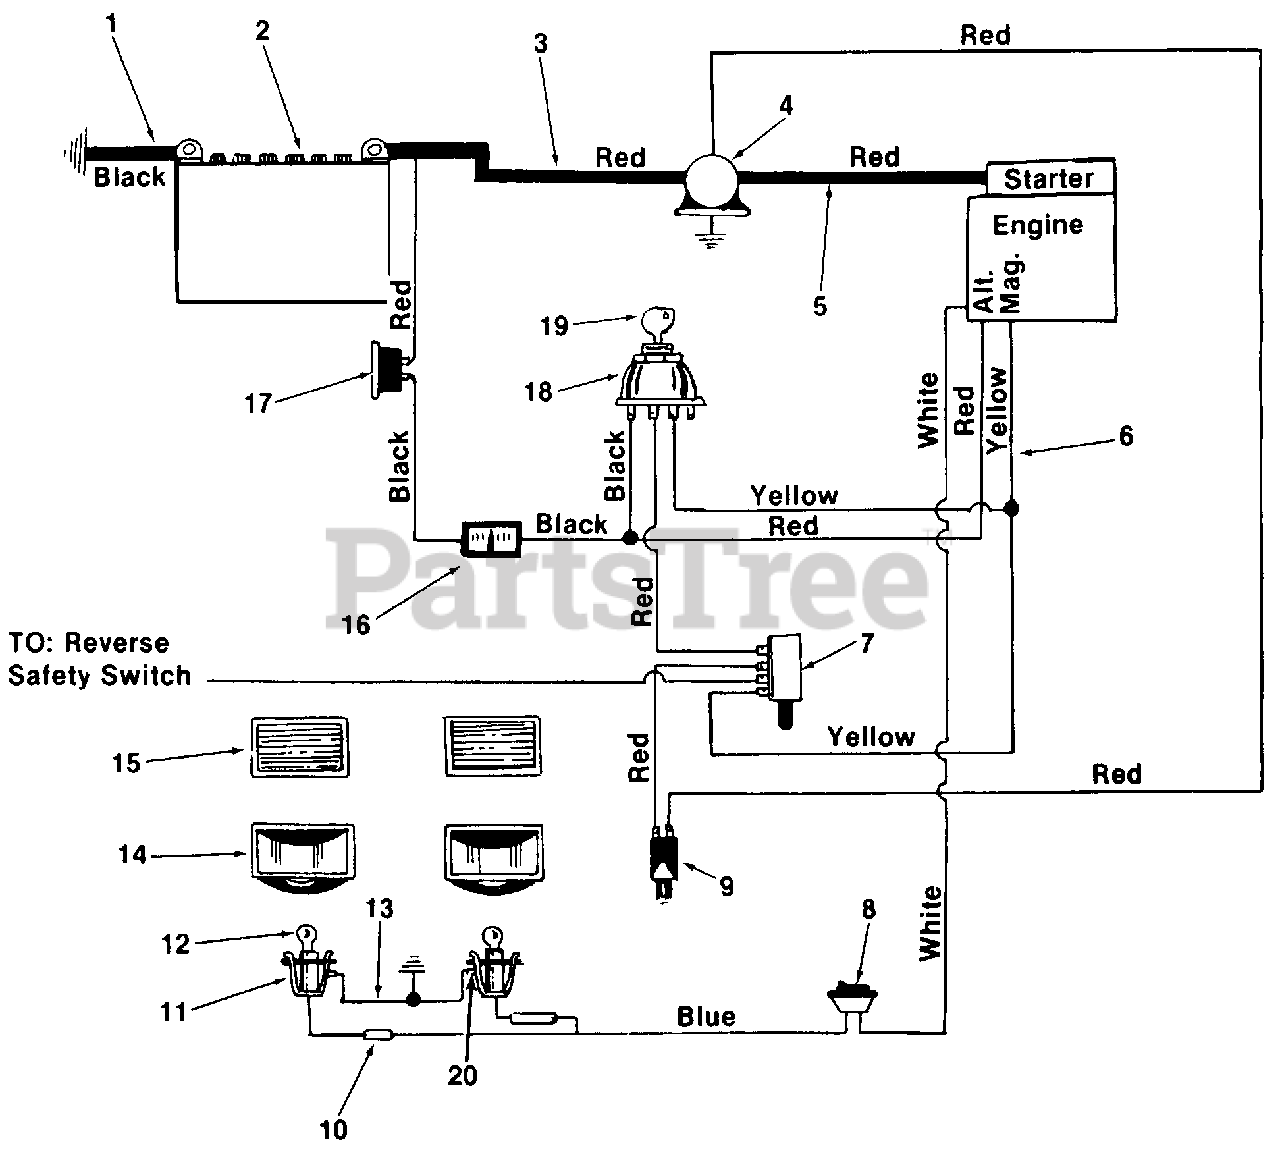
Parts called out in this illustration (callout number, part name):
1	Electric Wire
2	12V-Battery
3	Electric Wire
4	Solenoid
5	Electric Wire
6	Wire Harness
7	Safety Switch
8	Light Switch
9	Safety Switch
10	Tab Receptacle
11	Socket
12	Lamp
13	Ground Wire
14	Head Light Housing
15	Lens
16	Ammeter
17	Circuit Breaker
18	Ignition Switch
19	Ignition Key
20	Push On Ground Clip
